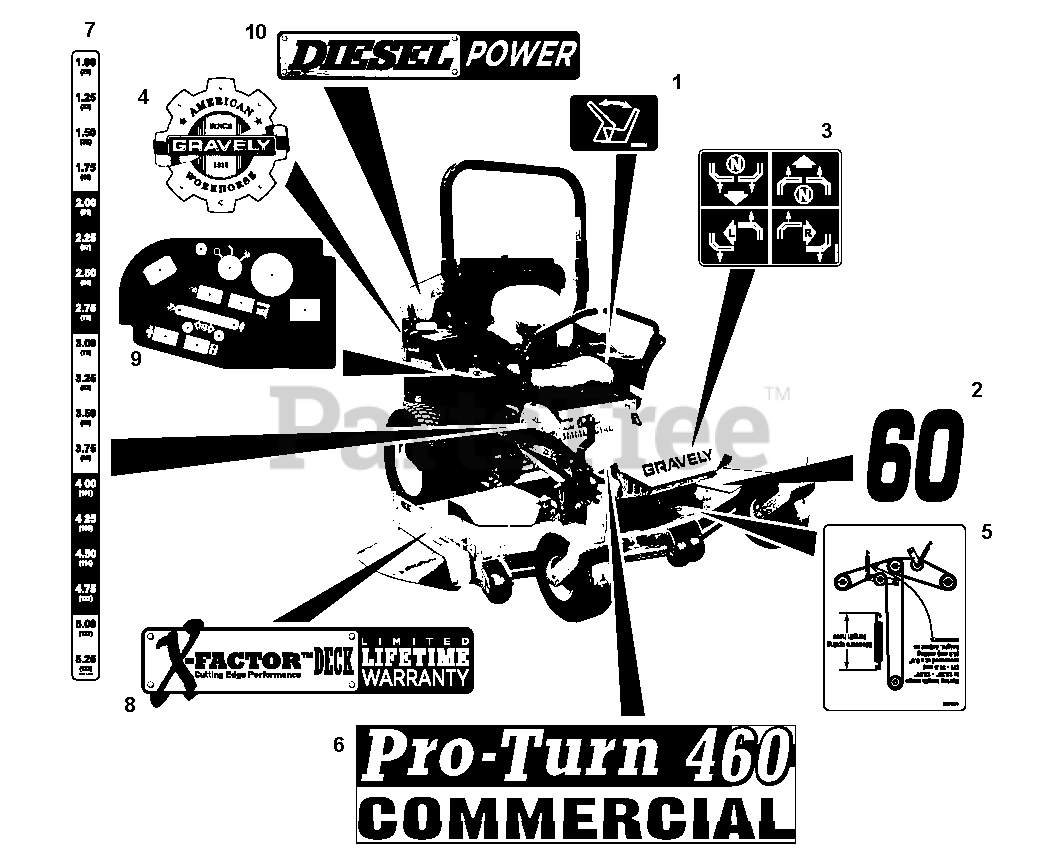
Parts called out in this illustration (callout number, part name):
1	Decal, Seat Release
2	Decal, 60 (992236)
3	Decal, Instructional Steering
4	Decal, Gravely Heritage
5	Decal, Belt Routing (992236)
6	Decal, Pro-Turn 460 (992236)
7	Decal, PT-400 Height of Cut
8	Decal, X-Factor Deck
9	Decal, Dash PT400 Diesel
10	Decal, Diesel Power
